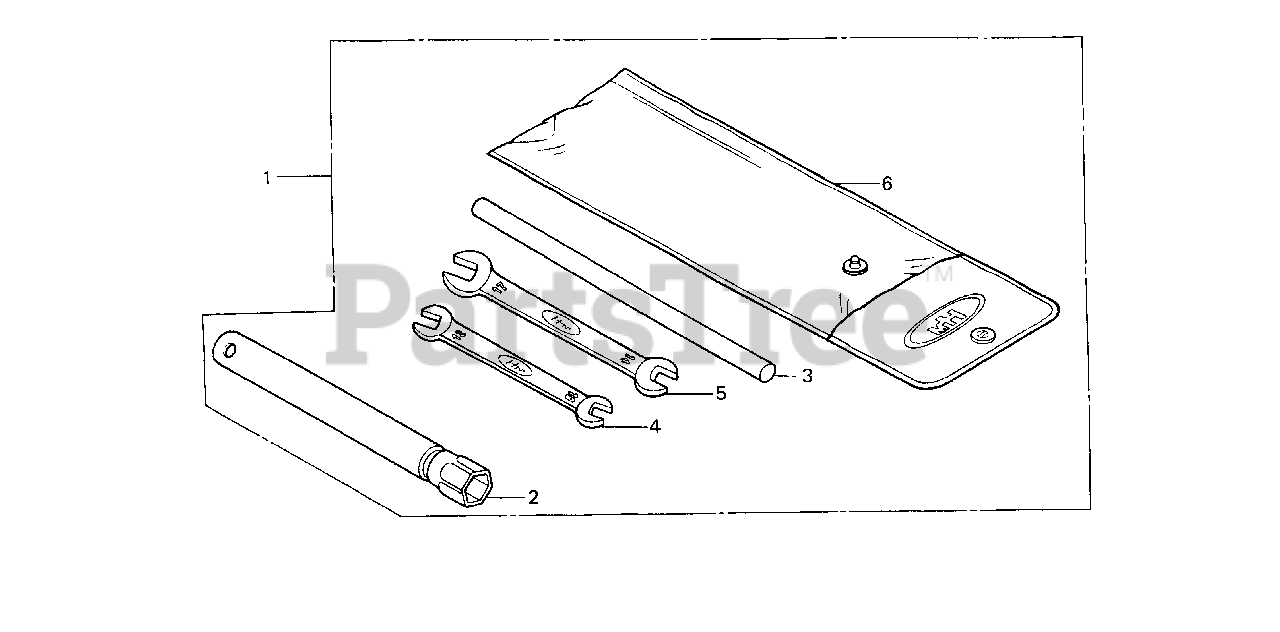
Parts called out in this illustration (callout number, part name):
1	TOOL KIT
2	WRENCH, SPARK PLUG
3	HANDLE, BOX WRENCH (NOT AVAILABLE)
4	WRENCH (10X12) (OPEN END)
5	WRENCH (14X17) (OPEN END)
6	BAG, TOOL (230MM)
